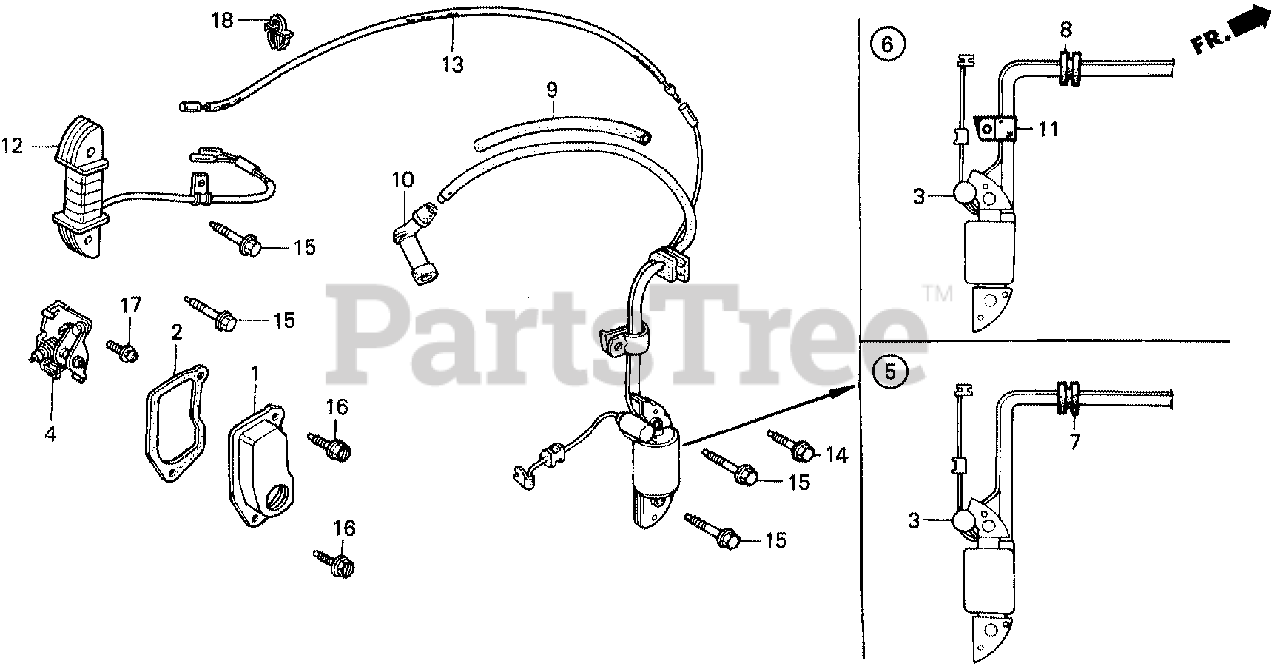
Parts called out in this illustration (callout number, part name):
1	COVER, POINTS
2	GASKET, POINT COVER
3	CONDENSER
4	POINTS ASSY.
5	COIL ASSY., IGNITION
7	GROMMET, WIRE
10	CAP ASSY., NOISE SUPPRESSOR
13	WIRE A, ENGINE STOP
15	BOLT, FLANGE (6X32)
16	BOLT, FLANGE (5X10)
17	SCREW-WASHER (5X12)
